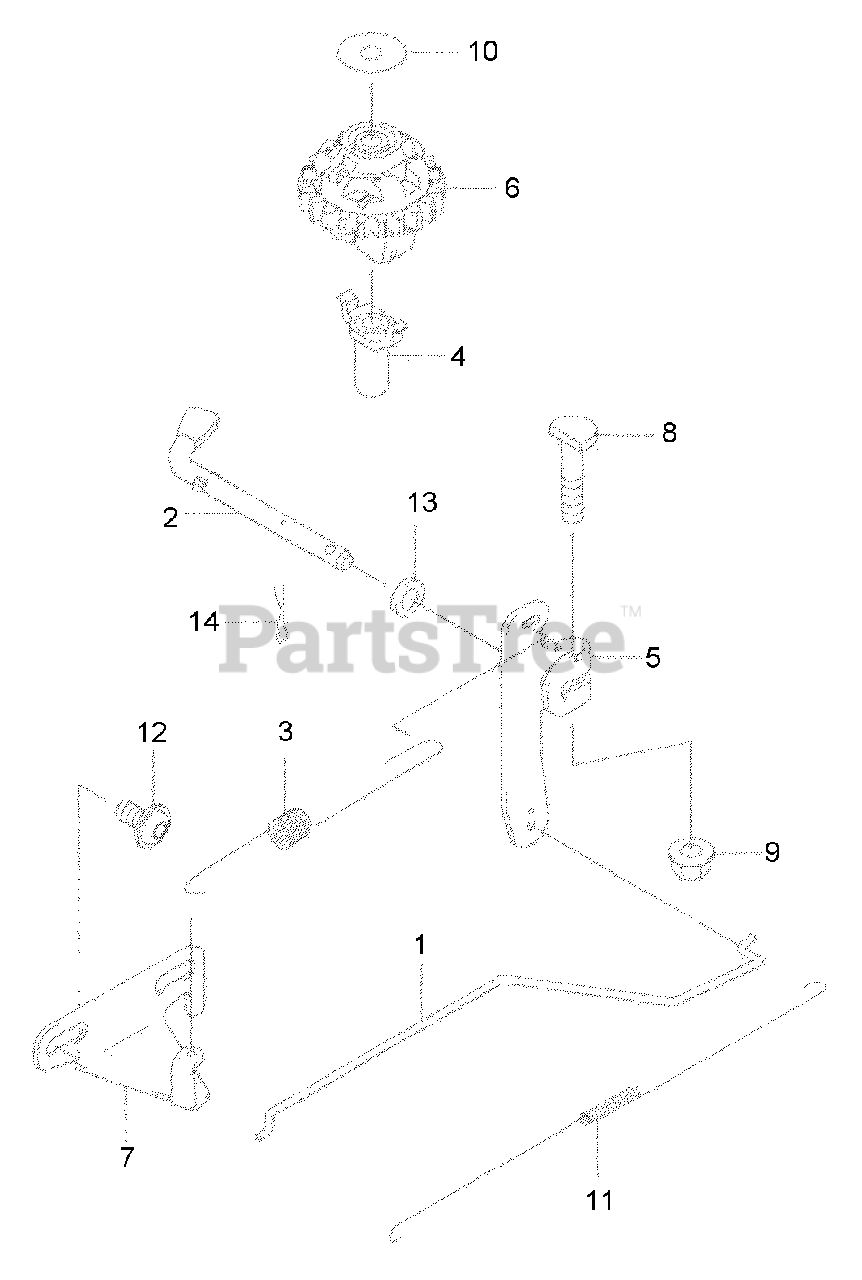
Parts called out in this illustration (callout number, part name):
1	Throttle Link
3	Governor Spring
6	Governor Assy.
7	Control Panel
9	Nut
11	Throttle Spring
12	Bolt, 6x12
13	Washer, 6.5x11.5x2.0
